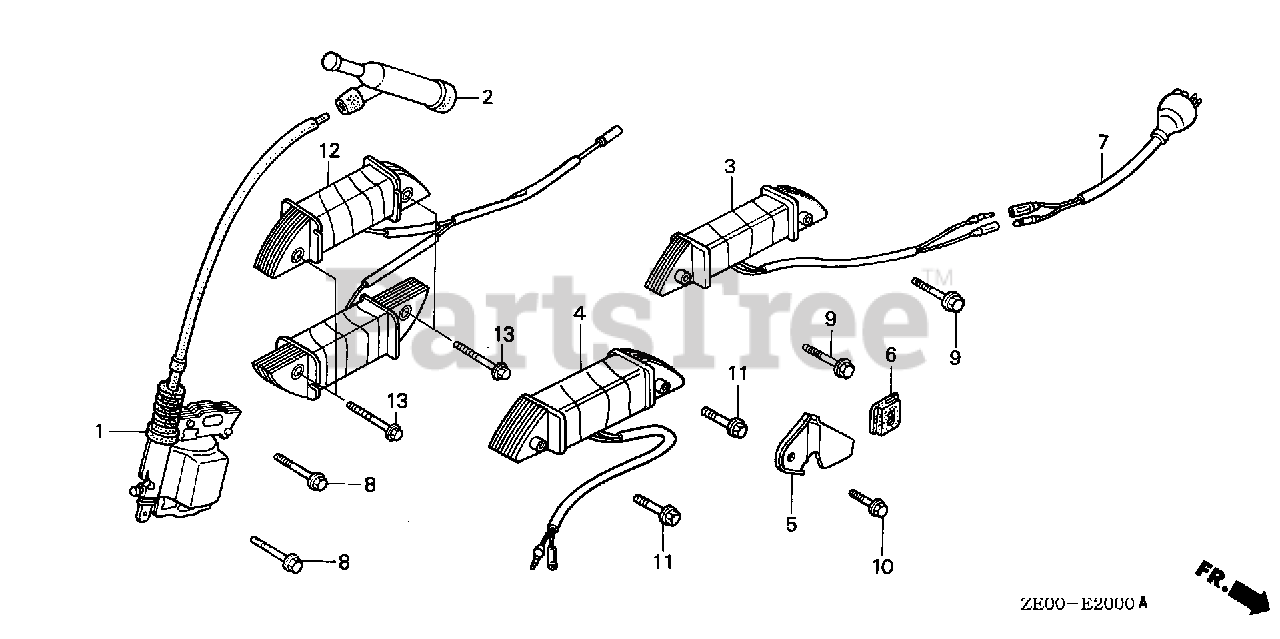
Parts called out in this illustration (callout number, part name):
1	COIL ASSY., IGNITION
2	CAP ASSY., NOISE SUPPRESSOR (NICHIWA Y-EZ RTFM256)
8	BOLT, FLANGE (6X28) (CT200)
8	BOLT, FLANGE (6X25) (CT200)
